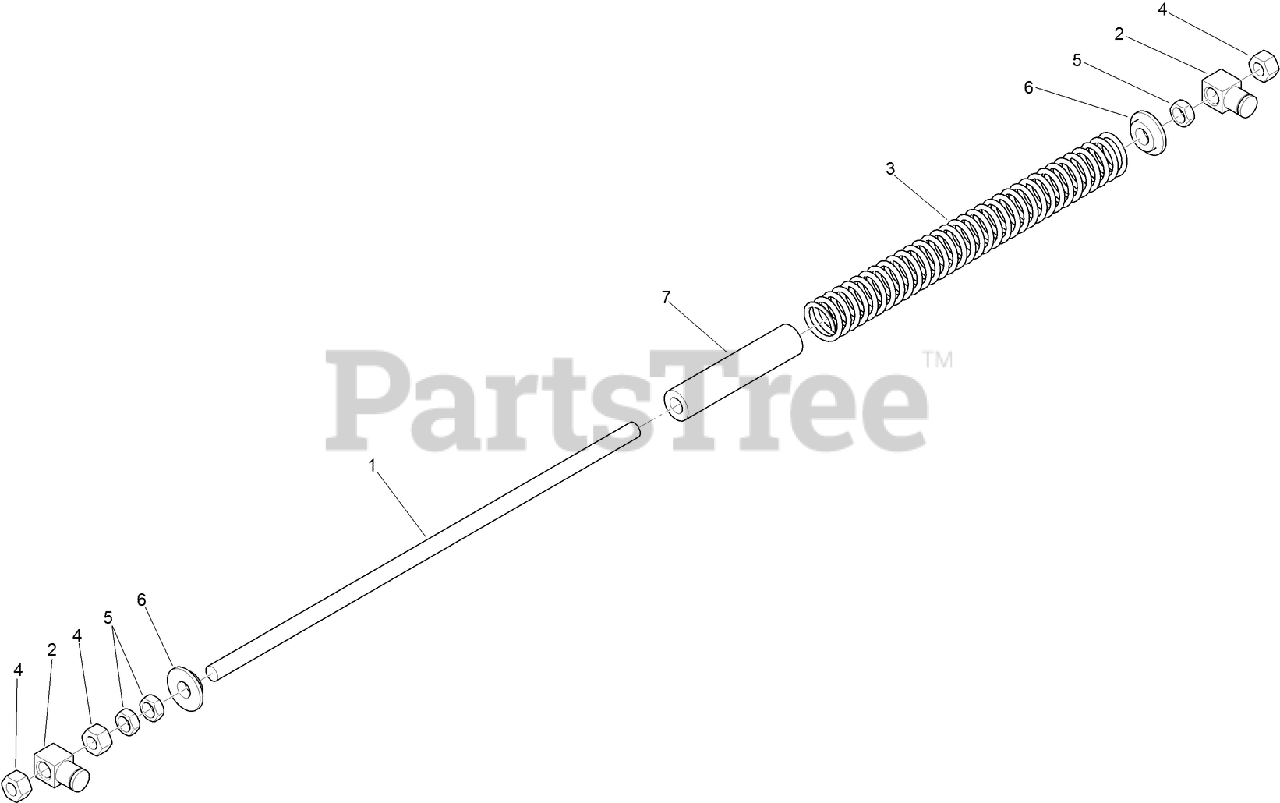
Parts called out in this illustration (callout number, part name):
1	ROD-LIFT, DECK
2	SWIVEL-DECK MOUNT, REAR
3	SPRING-COMPRESSION
4	NUT-HEX
5	NUT-JAM
6	WASHER-STEP
7	TUBE-GUIDE, SPRING
